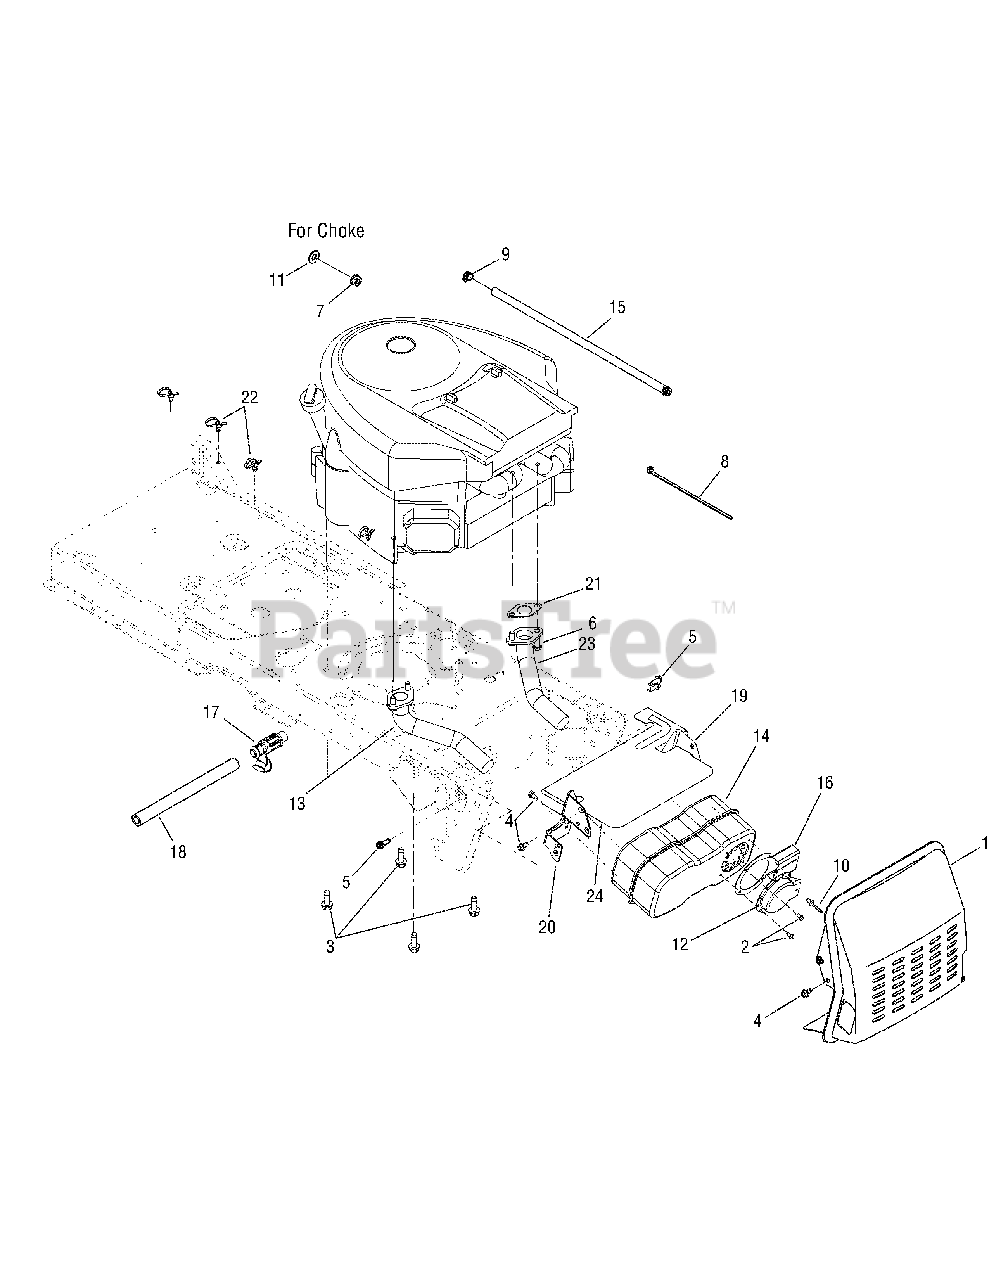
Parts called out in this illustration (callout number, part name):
1	Shield, Muffler
2	Screw, Hex Wash Hd. Tapp, #8-18 x .5
3	Screw, Hex Sems Tapp, 3/8-16 x 1.0
4	Screw, Hex Wash Hd. Tapp, 1/4-20 x .5
5	Screw, Hd. Tapp, 1/4-20 x .75
6	Screw, Hex Cap, 5/16-18 x .75 Gr5
7	Nut, Hex Flange Lock, 3/8-16 Gr5
8	Tie, Cable
9	Clamp, Hose
10	Rivet, Pop, .188 x .3
11	Washer, Flat, .406 x .875 x .059
12	Deflector, Muffler
13	Pipe Exhaust, RH
14	Muffler, Dual Inlet
15	Hose, Fuel ; Low Permeation, 51 inches
16	Deflector, Muffler
17	Valve, Oil Drain
18	Hose, Oil Drain Extension
19	Bracket, Muffler LH
20	Bracket, Muffler RH
21	Gasket, Exhaust
22	Tie, Push Mount
23	Pipe, Exhaust, LH
24	Shld., Heat, Twin
